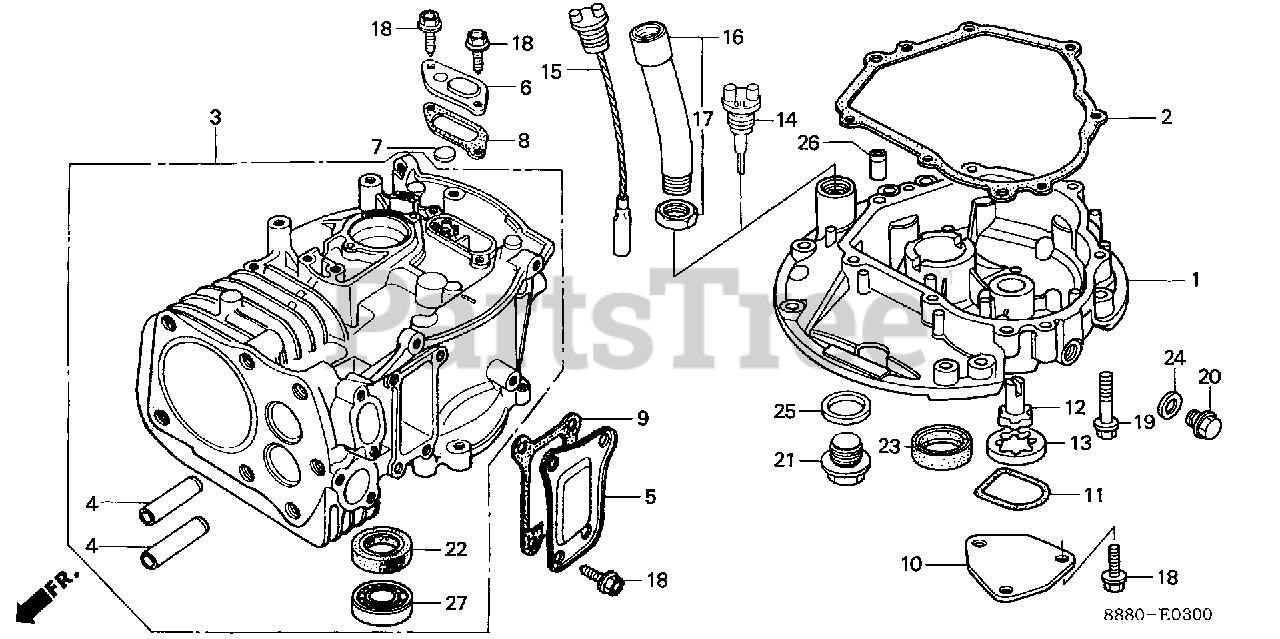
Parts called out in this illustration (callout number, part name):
1	PAN, OIL
1	PAN, OIL (NOT AVAILABLE)
2	GASKET, OIL PAN
3	CYLINDER ASSY.
3	CYLINDER ASSY. (NOT AVAILABLE)
4	GUIDE, VALVE (OVER SIZE)
5	COVER, TAPPET ROOM
6	CAP, BREATHER CHAMBER
7	VALVE, BREATHER
8	GASKET, BREATHER CAP
9	GASKET, TAPPET COVER
10	COVER, OIL PUMP
11	O-RING, PUMP COVER
12	ROTOR (INNER)
13	ROTOR, OIL PUMP (OUTER)
15	CAP, OIL FILLER
16	PIPE, OIL FILLER (NOT AVAILABLE)
17	NUT, OIL FILLER
18	BOLT, FLANGE (6X12) (CT200)
19	BOLT, FLANGE (6X32)
20	BOLT, DRAIN PLUG (12X15)
20	BOLT, DRAIN PLUG
21	BOLT, OIL DRAIN
22	OIL SEAL (25X41X6)
23	OIL SEAL (25X38X7)
23	OIL SEAL (25X38X7) (ARAI)
24	WASHER, DRAIN PLUG (12MM)
25	WASHER, DRAIN PLUG (20MM)
26	PIN, DOWEL (8X14)
27	BEARING, RADIAL BALL (6205)
